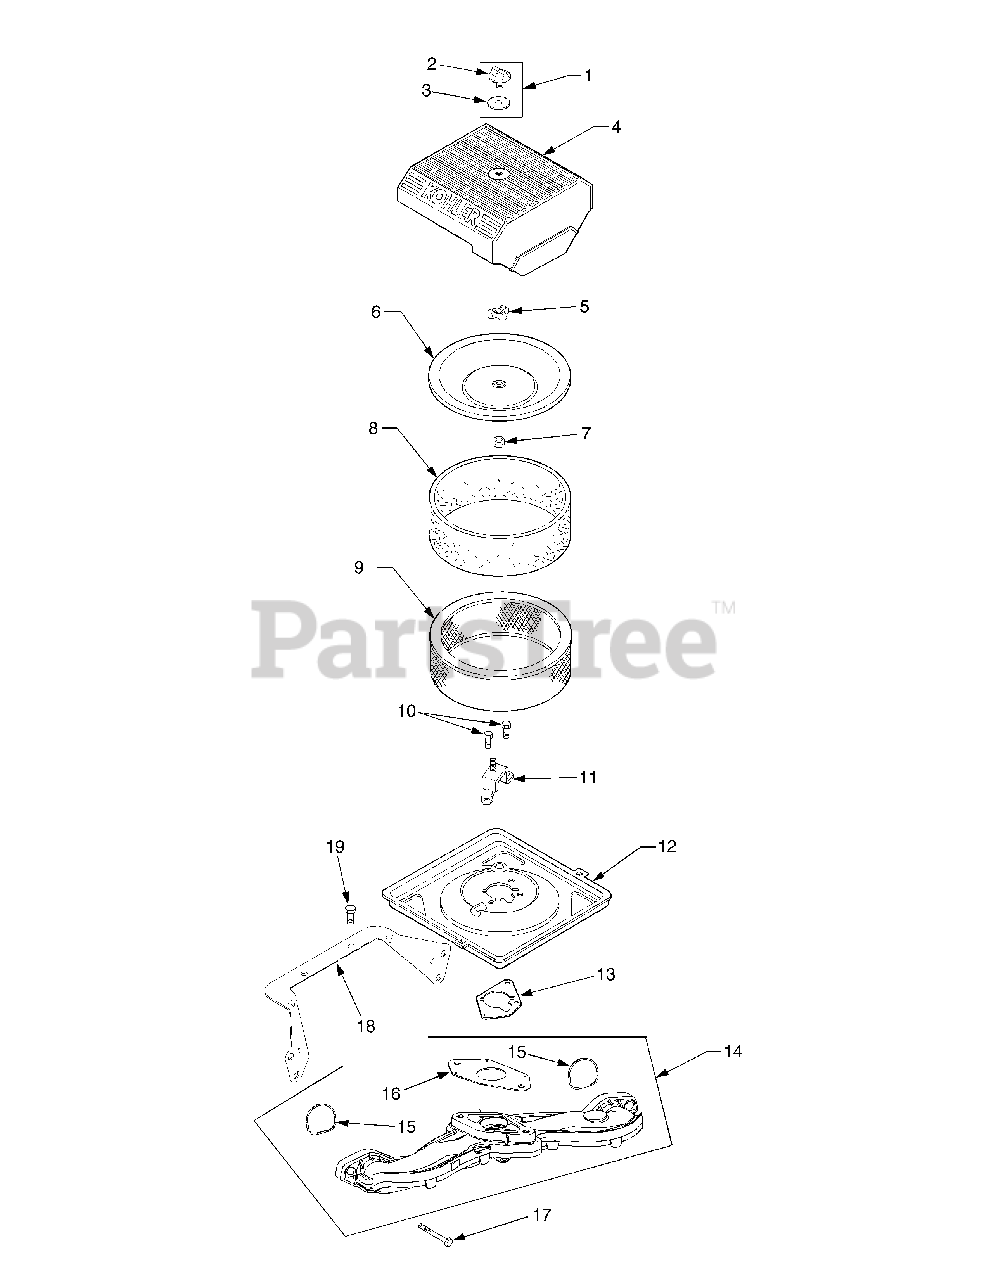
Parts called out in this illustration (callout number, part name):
1	Kit, Knob w/Seal (Incl. Ref #2,3)
3	Seal, Air Cleaner Cover Knob
4	Cover, Air Cleaner
6	Cover, Inner Air Cleaner
7	Seal, Inner Air Cleaner
8	Precleaner, Element, 71mm deep
9	Element, Air Cleaner, 74mm deep
10	Screw, Hex Flange, M6 x 1.0 x16
11	Bracket, Air Cleaner Base
12	Base, Air Cleaner
13	Gasket, Air Cleaner Base
14	Manifold, Intake (Includes Ref. Nos. 15 and 16)
15	O-Ring, Intake Manifold
16	Gasket, Carburetor
17	Screw, Hex Flange, M6 x 1.0 x 40
18	Bracket, Air Cleaner Base
19	Screw, Hex Flng, M5 x 0.8 x 10
